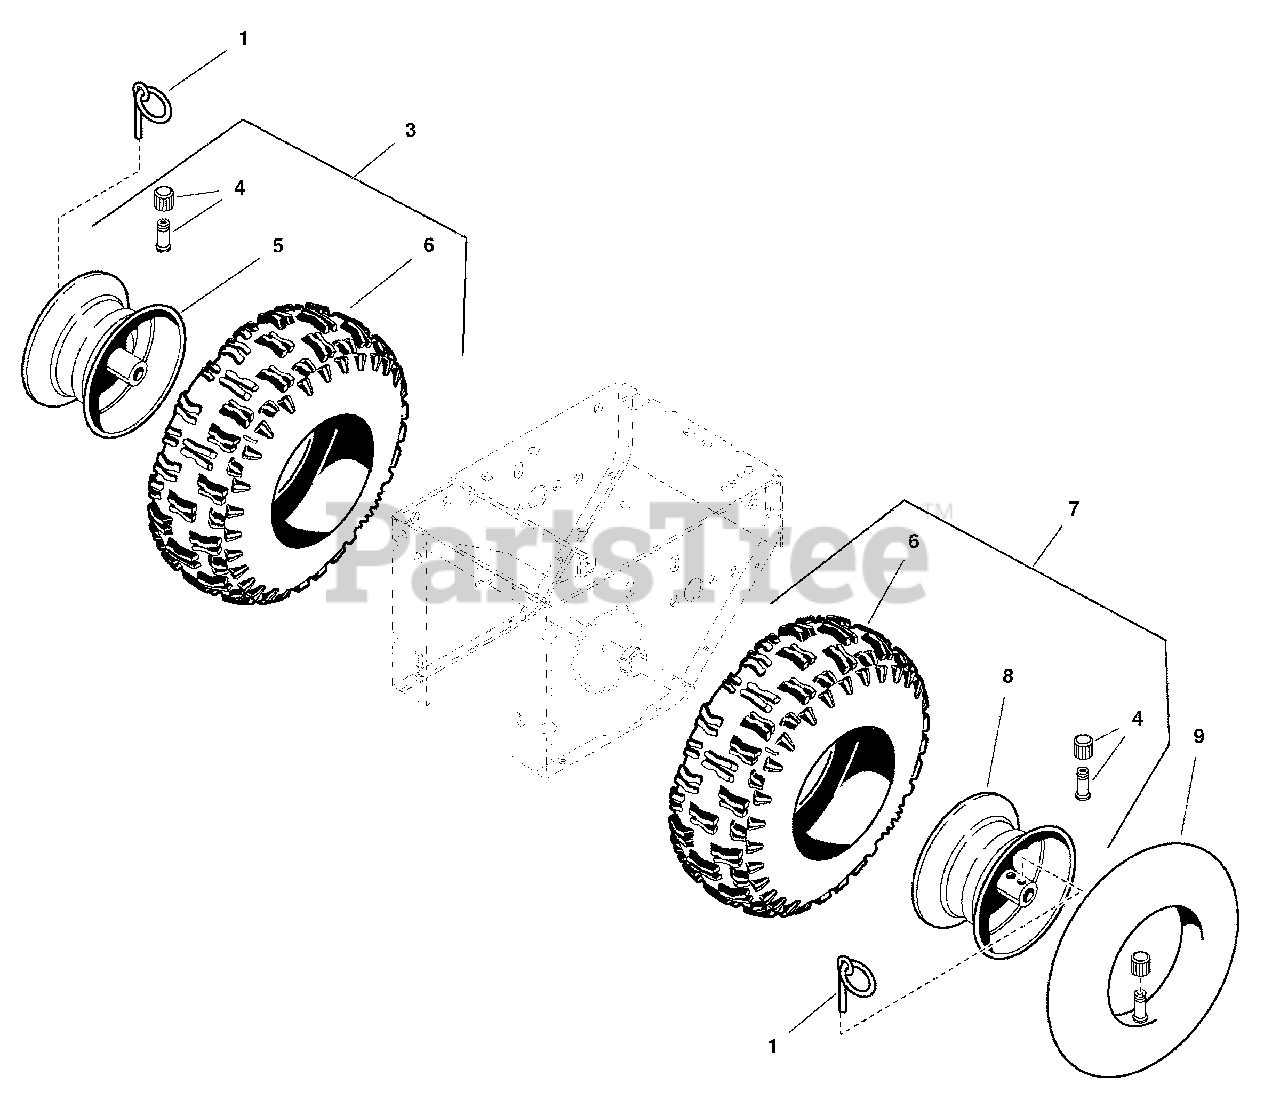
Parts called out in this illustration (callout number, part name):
1	PIN, KLIK, Ring
3	WHEEL & TIRE ASSEMBLY, Snow R.H.
4	VALVE STEM & CAP ASSEMBLY, Air
5	HUB, Wheel R.H., 3-3/4 Wide 8 Diameter 3/4 ID
5	HUB, Wheel, 5-3/8 Wide 8 Diameter 3/4 ID
6	TIRE, 4.80/4.00-8, X-TRAC TL
6	TIRE, 16 x 6.5-8 X-TRAC TL
7	WHEEL & TIRE ASSEMBLY, Snow L.H.
8	HUB, Wheel L.H., 3-3/4 Wide 8 Diameter 1-1/8 ID
8	HUB, Wheel 5-3/8 Wide 8 Diameter 1-1/8 ID
